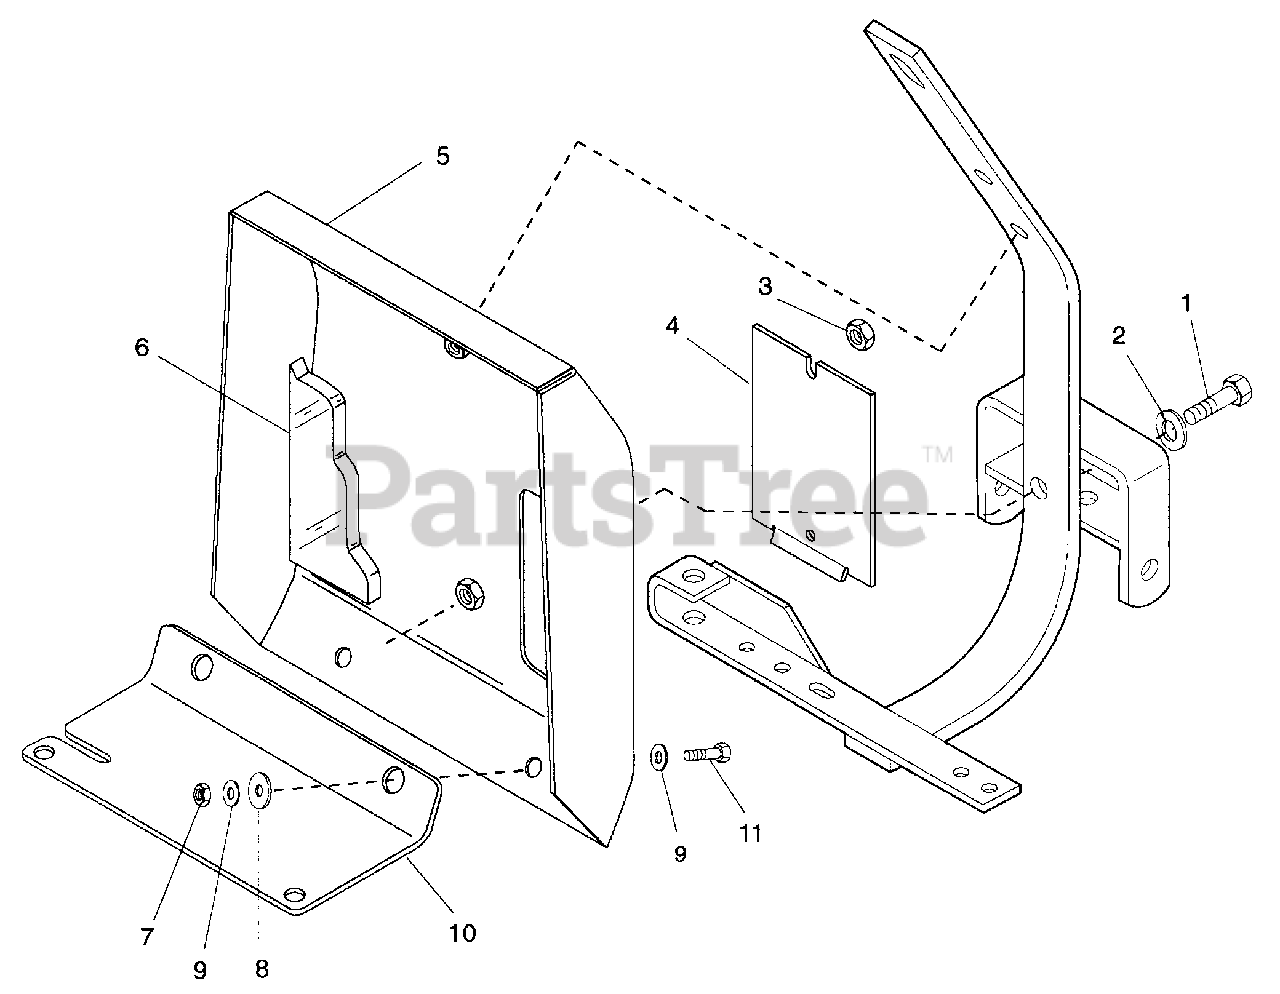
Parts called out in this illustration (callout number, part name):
1	Bolt-Hex .50-13 x 1.25 Grade 5
2	Washer-Lock .50
3	Nut-Jam-Nylon .250-20
4	Plate, Door
5	Weldment, Sound Shroud
5	Weldment, Shroud
6	Foam, Door
6	Foam, Middle
6	Foam, Right Hand
6	Foam, Left Hand
7	Nut-Locking-Nylon .250-20
8	Washer-Flat-Steel .281 x 1.250 x .062
9	Washer-Flat-Steel .281 x .620 x .065
10	Screen, Sound
11	Bolt-Hex .25-20 x .63
